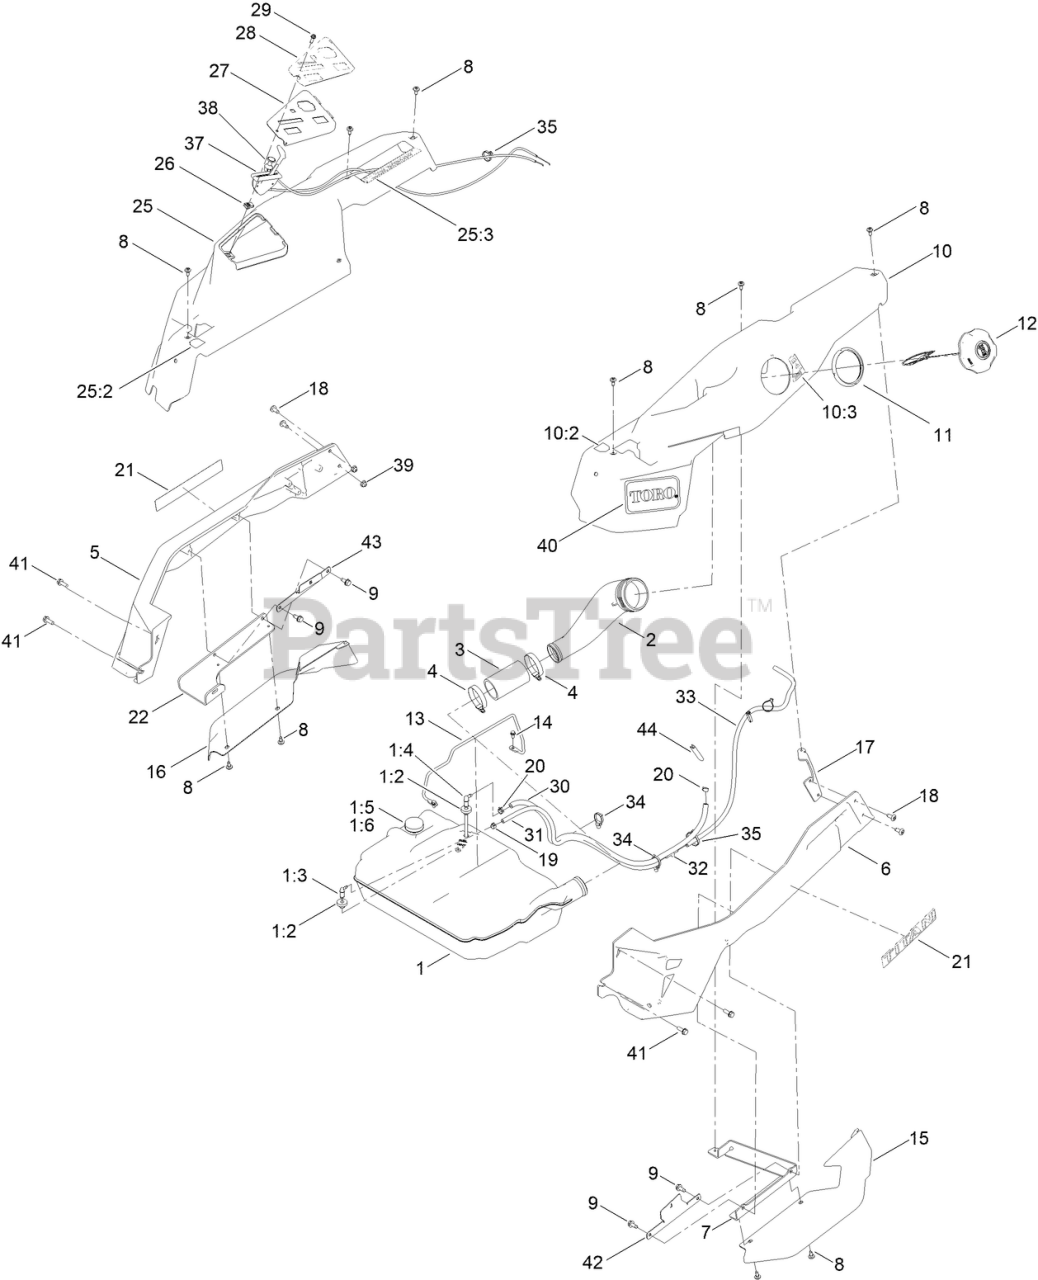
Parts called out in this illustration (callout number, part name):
1	TANK ASM - FUEL
1:2	BUSHING
1:3	FITTING-ELBOW 90
1:4	FITTING - PICKUP, FUEL
1:5	GROMMET-FUEL
1:6	REMOTE GAUGE ASM
2	NECK-FILLER, FUEL
3	HOSE-FILLER, FUEL
4	CLAMP-HOSE
5	CAST-TUBE, RH [RED]
6	CAST-TUBE, LH [RED]
7	MOUNT-POD BRACKET LH
8	SCREW-SHOULDER
9	SCREW-HWHTF
10	POD ASM - LH W/DECALS
10:2	DECAL-CONTROL LEVER, LH
10:3	DECAL-FUEL FILL
11	RING-RETAINING
12	CAP-FUEL, RATCHETING
13	ROD-HOLD DOWN
14	SCREW-HWH
15	FENDER-TIME CUTTER, LH
16	FENDER-TIME CUTTER, RH
17	BRACKET-REAR POD, LH
19	CLAMP-HOSE
20	CLAMP-HOSE
21	DECAL-TITAN
22	BRACKET-MR SPRING
25	POD ASM - RH , MR W/DECALS
25:2	DECAL-CONTROL LEVER, RH
25:3	DECAL - MYRIDE
27	PANEL-CONTROL
28	DECAL - CONTROL PANEL
29	SCREW-HWHTF
30	HOSE-FUEL
31	HOSE-FUEL
32	ADAPTER ORIFICE
33	HOSE-LP
34	CLIP-TIE
35	TIE-CABLE
37	CABLE-THROTTLE
38	CABLE-CHOKE
39	NUT-HF
40	DECAL - TORO LOGO
41	SCREW-TAPTITE
42	BRACKET-ALIGNMENT, POD LH
43	BRACKET- ALIGNMENT, POD RH MR
44	TRIM-EDGE GUARD
